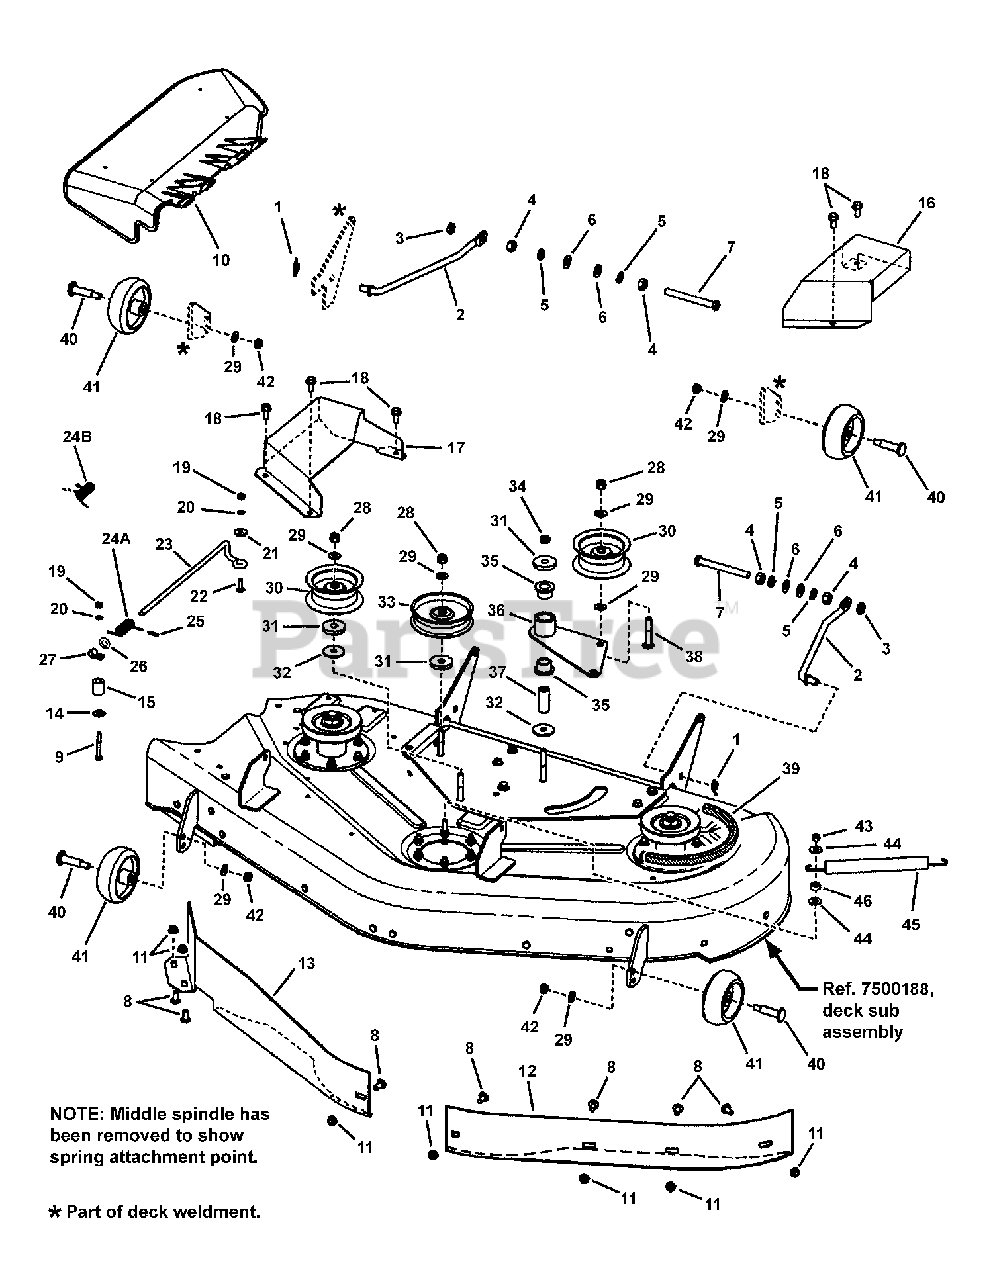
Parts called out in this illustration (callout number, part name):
1	COTTER PIN, 1/2 Self Locking, YZ
2	ROD, Stabilizer
3	NUT, 7/16-20 Hex Center Lock Jam, GR 5 or B
4	NUT, 7/16-20 Hex, GR 5 or B
5	WASHER, 7/16" Split Lock
6	WASHER, .47 x .92 x .065 Flat
7	SCREW, 7/16-20 x 4" Hex Head Cap, GR 5
8	BOLT, 5/16-18 x 3/4" Short Neck Carriage, GR 5
9	SCREW, 1/4-20 x 2" Hex Head Cap, GR 5
10	DEFLECTOR, Plastic
11	NUT, 5/16-18 Hex Flange Lock, GR 5
12	BAFFLE, Blowout, LH, 44" Mower
13	BAFFLE, Blowout, 44" Mower
14	RETAINER, 1/4" Bolt
15	SPACER, .380 ID x .750 OD x .895
16	COVER, Spindle, LH, Red, RZT 44/50"
17	COVER, Spindle, RH, Red, RZT 44/50"
18	SCREW, 5/16-18 x 3/4" Hex Washer Self-Tap
19	NUT, 1/4-20 Hex
20	LOCKWASHER, 1/4" Spring
21	WASHER, Large, 1/4 ID x 5/8 OD x .134/.109
22	BOLT, 1/4-20 x 7/8" Round Head Short Square Neck, GR 5
23	ROD, Deflector
24A	SPRING, Torsion
24B	SPRING, Torsion, Chute 44/50
25	CAP, Spring End
26	WASHER, .34 ID x .75 OD Flat
27	CLAMP
28	NUT, 3/8-16 Hex Nyloc
29	WASHER, 3/8" Flat SAE
30	PULLEY, Flat Idler, 3-1/4" Dia.
31	WASHER, .468 x 1.625 x .25 Flat
32	WASHER, .406 x 1.50 x .120 Flat
33	PULLEY, 4" Flat Idler
34	NUT, Hex Cap Lock 3/8-16
35	BEARING, 3/4" I.D.
36	WELDMENT, Idler Swing Arm
37	IDLER SPACER, .75 x .390 x 1.800
38	BOLT, 3/8-16 x 2-1/4" Round Head Short Square Neck, GR 5
39	BELT, 44" Deck, 138.25" E.L. HB Section
40	SHOULDER BOLT, 3/8-16 x 3/4" YZ
41	WHEEL, 4 x 1-7/8" Offset
42	NUT, 3/8-16 Hex Center Lock
43	NUT, 5/16-18 Hex Center Lock, GR 5 or B, YZ
44	WASHER, 3/8" Flat
45	SPRING, Idler Primary
46	SPACER, .340 I.D. x .63 O.D. x .310 Thick
